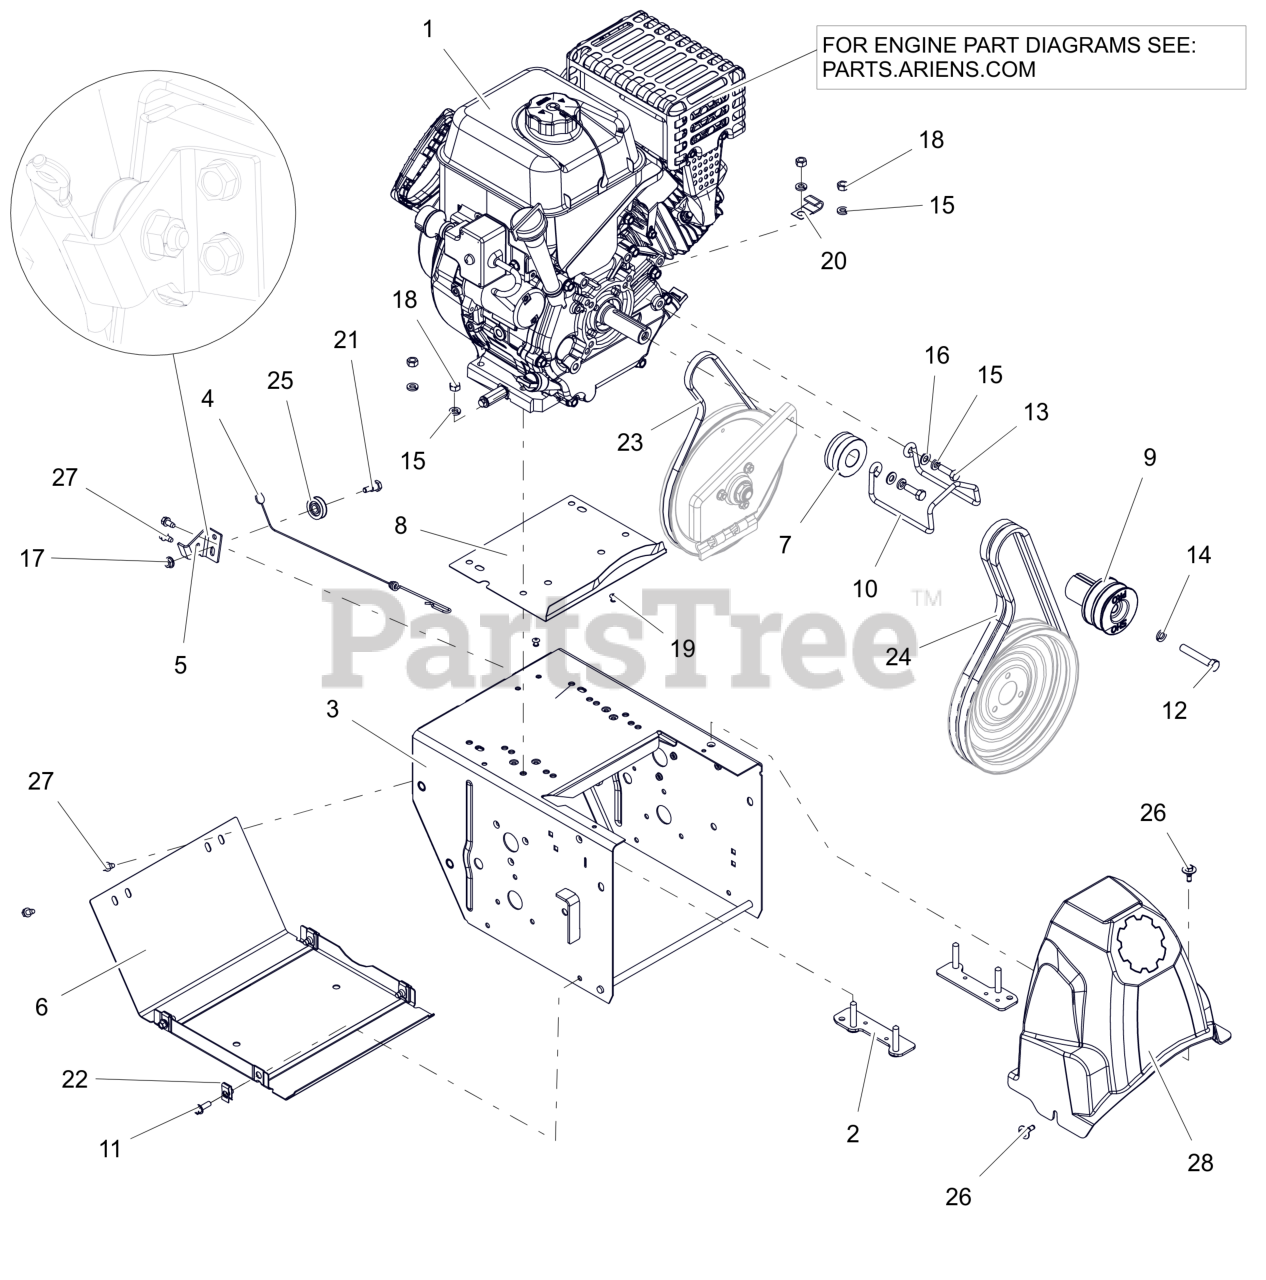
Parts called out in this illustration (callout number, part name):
1	ENGINE, ARIENS AX291 240V/60W
2	STRAP, ENGINE-MEDIUM BLOCK
3	FRAME, MAIN - 14GA DELUXE (ORANGE)
4	CABLE, LOWER TRACTION,SS & PRO
5	BRKT, CABLE PULLEY
6	COVER, BOTTOM
7	SHEAVE, TRACTION (KEYLESS)
8	BAFFLE, WATER - LARGE BLOCK
9	SHEAVE,ATTACHMENT-SHO 2 GRV
10	FINGER, BELT
11	BLT, HWH .25-20X.75 G5 ZCC
12	BLT, HEX .38-24X2.25 G5 ZCC
13	BLT, HEX 0.3125-24X1 G5 ZCC
14	WSHR,LK-REG .375X.094 ZCC
15	WSHR, LK-HVY .312X.097 ZCC
16	WSHR,FLT .344X.688X.065 ZCC
17	NUT-LK-TOP-FLG .250-20 GF ZCC
18	NUT, HEX .312-18 ZCC
19	RVT, POP .1875 ZCC
20	J-CLAMP
21	BOLT, SHLDR -.375 X .375 X .25-20
22	NUT-RTNR .25-20X.56
23	V-BELT, 3L-WRAPPED
24	V-BELT, HA-RAW EDGE (SET)
25	PULLEY, CABLE
26	SCR-TAP .25-20X.5 CAPTIVE
27	SCR-TAP .25-20X.50 HWH ZCC
28	COVER, BELT
